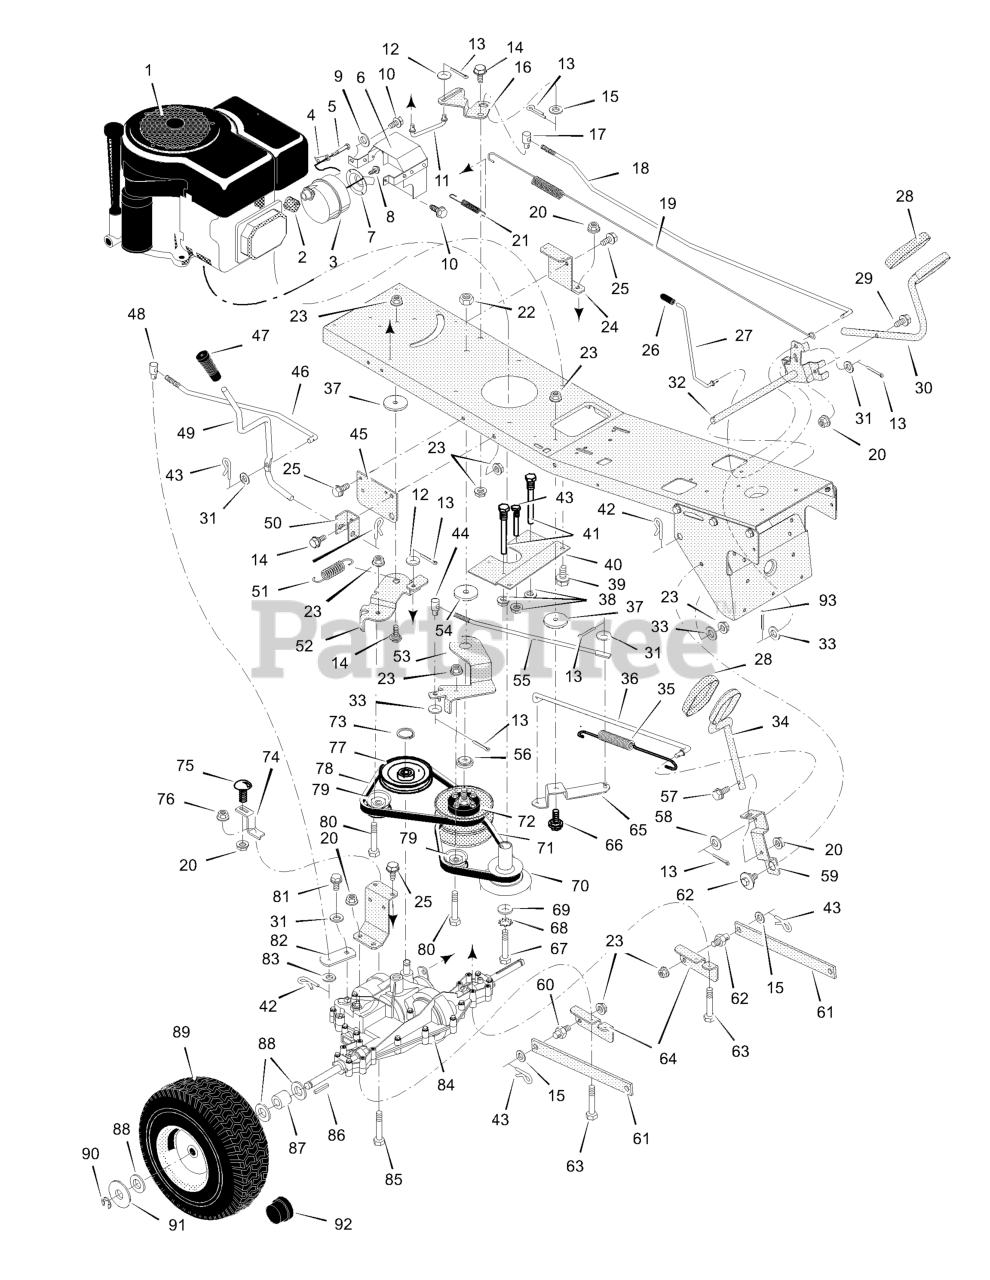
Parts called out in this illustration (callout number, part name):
1	Engine
2	GASKET, Exhaust
3	Muffler
4	Lock, Muffler Screw
5	Bolt, Hex
6	Shield, Heat
7	Tube, Exhaust
9	Washer, Lock
10	Screw
11	Rod, Link
13	Pin, Cotter
14	Bolt, Shoulder
15	Washer
16	Link, Clutch
17	NUT, Adjusting, 1/2-13
18	Rod, Clutch Variator
19	Spring, Brake
20	Nut
21	Spring, Brake Return
23	Nut
24	Bracket, Transaxle -Left
27	Rod, Parking Brake
28	Pad, Pedal
29	Bolt, Hex
30	Rod, Clutch/Brake
32	Rod, Clutch/Brake Pivot
33	Washer
34	Pedal, Variator
35	Spring, Return
36	Rod, Variator Connect
38	Nut
39	Screw
40	Plate, Belt Guide
41	Guide, Belt -Long
42	Pin, Hair
43	Guide, Belt -Short
44	Nut, Adjusting
45	Bracket, Lift Pivot
46	Rod, Shift Link
47	Grip
48	Nut, Adjusting
49	Lever, Shift
50	Bracket, Pivot
51	Spring - Variator Drive
52	Arm, Idler
53	Arm, Clutch Idler
55	Link, Drive
57	Bolt
58	Washer
59	Arm, Pedal
60	Bolt, Shoulder
62	Pin, Threaded
63	Bolt, Hex
64	Bracket, Rear Hanger
65	Link Assembly, Pivot
66	Bolt, Shoulder
67	Bolt, Hex
68	Lockwasher
70	Pulley Stack
71	Belt, Primary Drive
72	Pulley Assembly, Variator
73	Ring, Snap
74	Bracket, Torque Reactor
75	Bolt, Carriage
76	Nut, Stoverlock
77	Pulley, Transaxle
78	Belt, Secondary Drive
79	Pulley, Idler
80	Bolt, Hex
81	Cap Screw
82	Yoke, Shift
84	Transaxle
85	Bolt, Hex
86	Key, Square
87	SPACER, Rear Wheel
89	Wheel & Tire Assembly
92	Hub Cap
93	Pin, Cotter
94	Plate, Reinforecement
95	Bracket, Transaxle -Right
